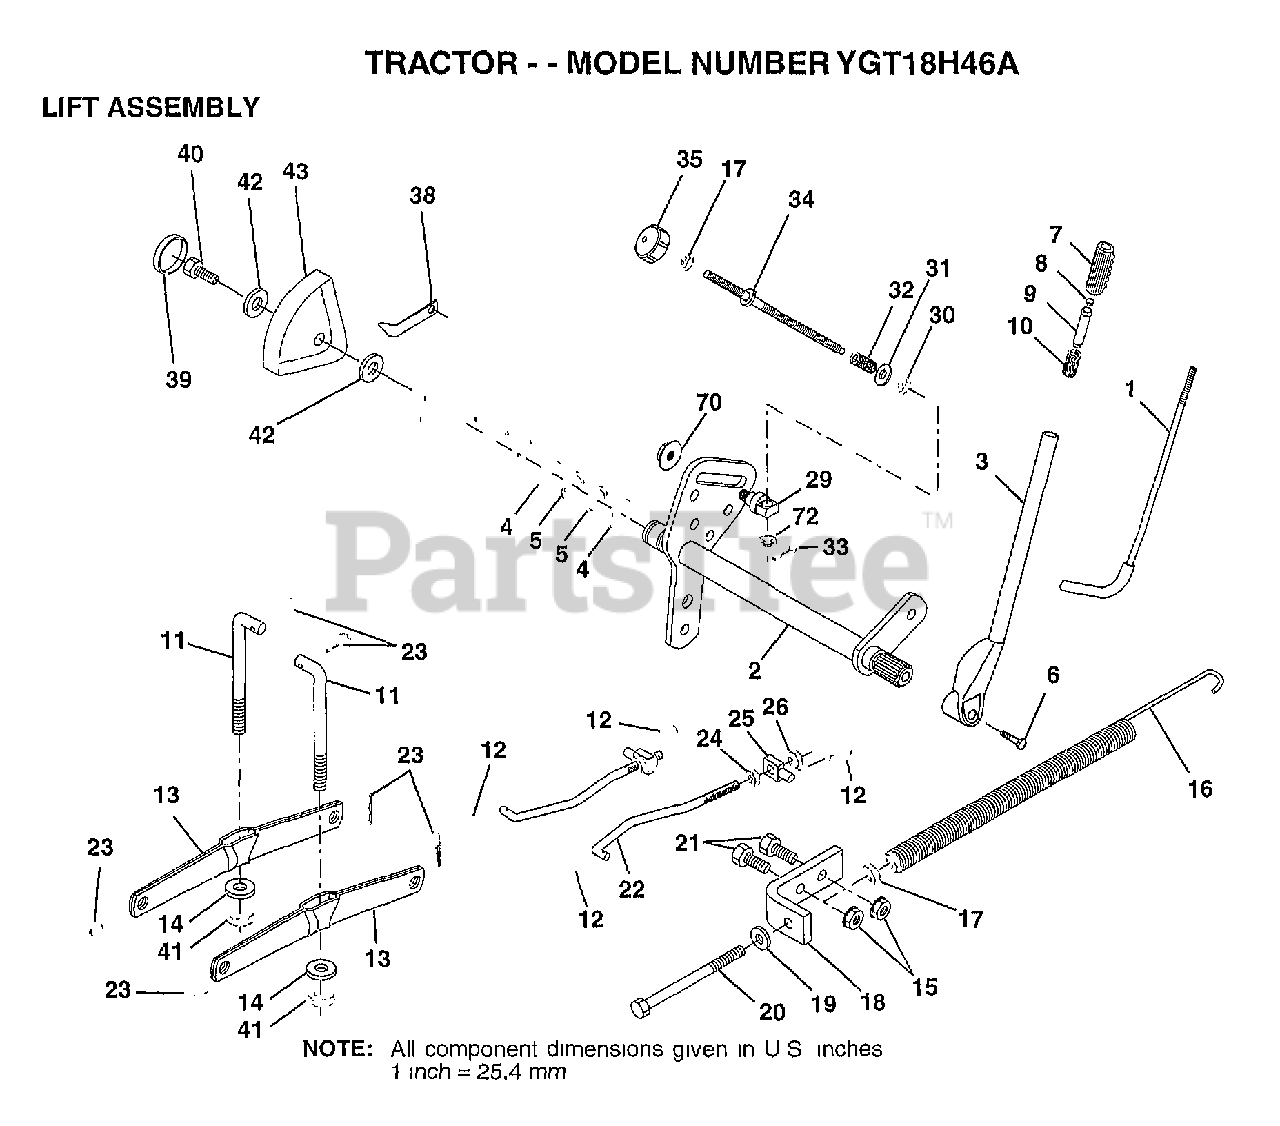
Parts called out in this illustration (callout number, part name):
1	LEVER ROD LT
2	SHAFT AMS LIFT
4	E-RING
5	WASHER
6	"BOLT,HEX"
7	GRIP HANDLE
10	SPRING T
11	LINK.LIFT.MWR.VGT
12	RETAINER.SPRING
13	ARM SUSP REAR
14	BEARING PVT LH
17	NUT
18	BRACKET SPRING AS
19	WASHER
20	BOLT-ADJ SPRING T
21	BOLT
22	LINK.FRONT
24	NUT
25	TRUNION
26	NUT.LK.W/WSH.1/2.
29	TRUNNION
30	NUT T
31	WASHER
32	SPRING.COMP.INF.H
34	ROD.ADJ.LIFT
35	KNOB INF 3/8-16
38	POINTER-INDICAT
39	"PLUG,HOLE"
40	SCREW
41	NUT.CROWNLOCK.3/8
42	WASHER
43	HEIGHT INDICATOR
70	NUT.HXFLG.LOCK.
72	NUT PUSH M
